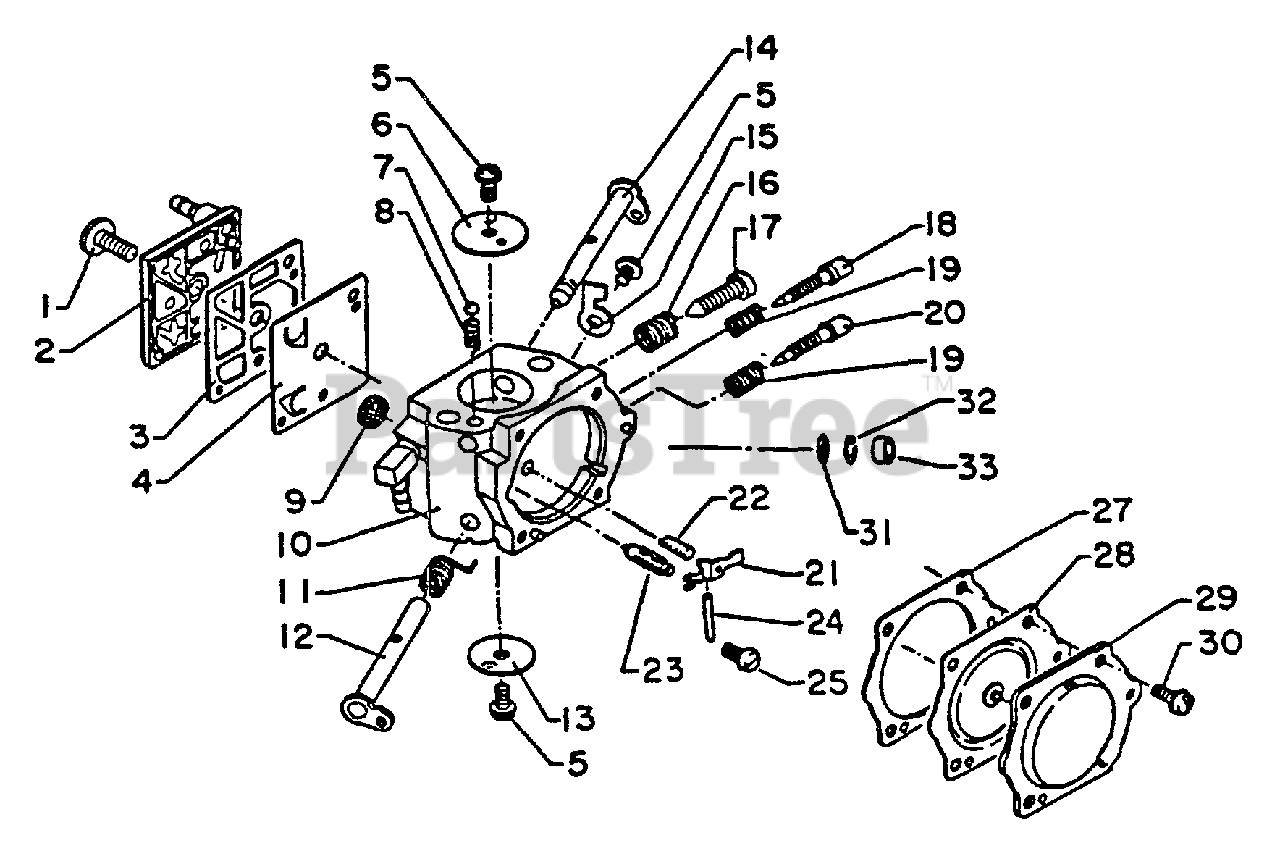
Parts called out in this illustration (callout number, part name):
2	COVER, PUMP
3	GASKET, FUEL PUMP
4	DIAPHRAGM, FUEL PUMP
6	VALVE, THROTTLE
7	BALL, CHOKE FRICTION
9	SCREEN, FUEL INLET
10	BODY, CARBURETOR
11	SPRING, THROTTLE
12	SHAFT, THROTTLE
13	VALVE, THROTTLE
14	SHAFT, CHOKE
15	STOP, THROTTLE
16	SPRING, IDLE ADJUST
17	SCREW, IDLE ADJUST
18	NEEDLE, IDLE
19	SPRING, NEEDLE
20	NEEDLE, HIGH SPEED
21	LEVER
23	VALVE, INLET NEEDLE
24	PIN, METERING LEVER
25	SCREW, METERING LEVER PIN
27	GASKET, METERING DIAPHRAGM
28	DIAPHRAGM, METERING
29	COVER, METERING DIAPHRAGM
31	SCREEN, SPARK ARRESTER
32	RING, RETAINING
33	PLUG, CUP
